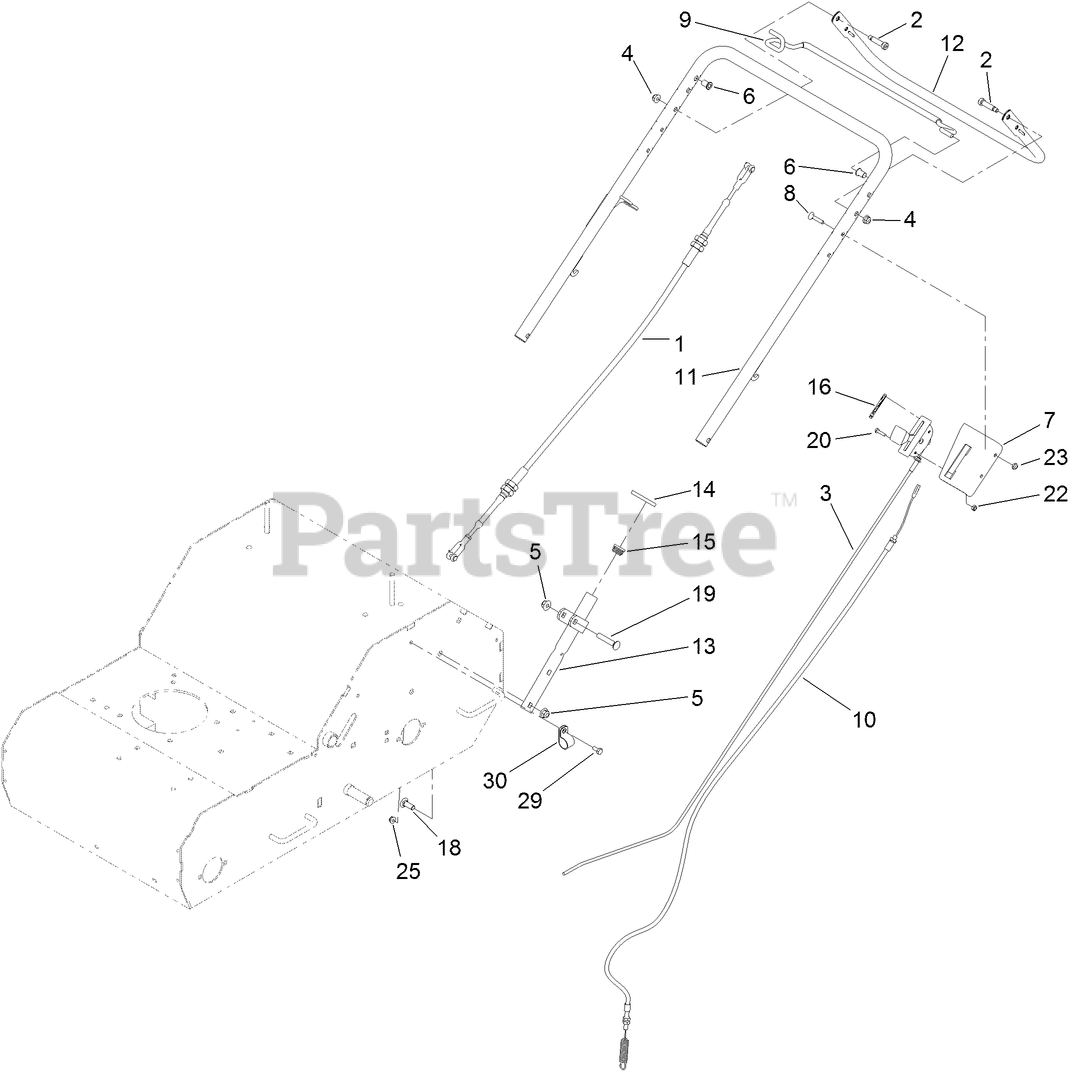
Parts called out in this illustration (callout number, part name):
1	CABLE-PUSH/PULL
2	BOLT-SHOULDER
3	CONTROL-THROTTLE
4	NUT-HF, NI
5	NUT-HF, NI
6	BUSHING
7	BRACKET-THROTTLE
8	BOLT-HANDLE
9	BAIL-TRACTION
10	CABLE-IDLER
12	TUBE-LIFT HANDLE
13	MOUNT-HANDLE
14	RING-HANDLE LOCK
16	DECAL-THROTTLE/CHOKE
18	SCREW-CARR
19	SCREW-CARR
20	SCREW-PPH
22	NUT-LOCK, NI
23	NUT-LOCK, NI
25	NUT-HF
29	SCREW-HH
30	CLAMP-R
